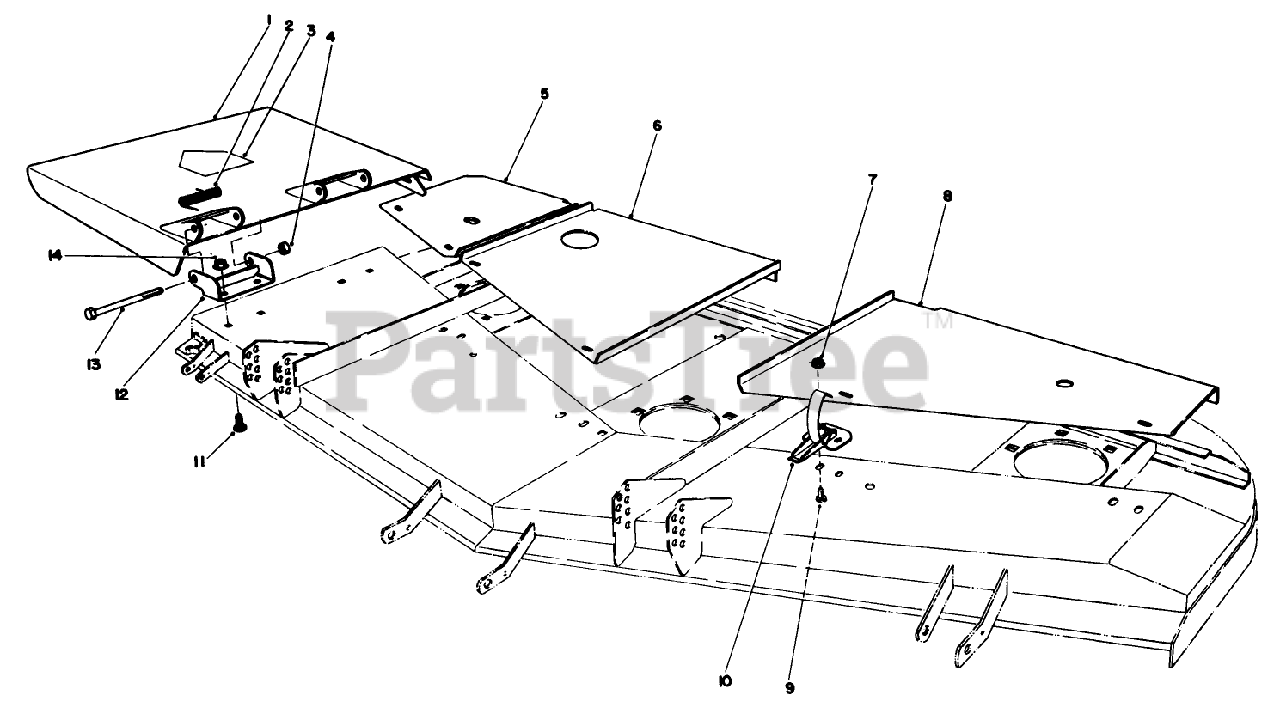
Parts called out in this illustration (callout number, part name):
1	Deflector Assembly (Incl. Ref. #3)
2	SPRING
3	DECAL-DANGER
4	NUT-HEX
5	Cover R.H.
6	Cover-Center
7	NUT-LOCK, FLANGE
8	Cover L.H
9	SCREW-HWH
10	CLAMP-SLOTTED
11	SCREW-CARR
12	Bracket-Hinge
13	SCREW-HH
14	NUT-HHF, WHIZ
